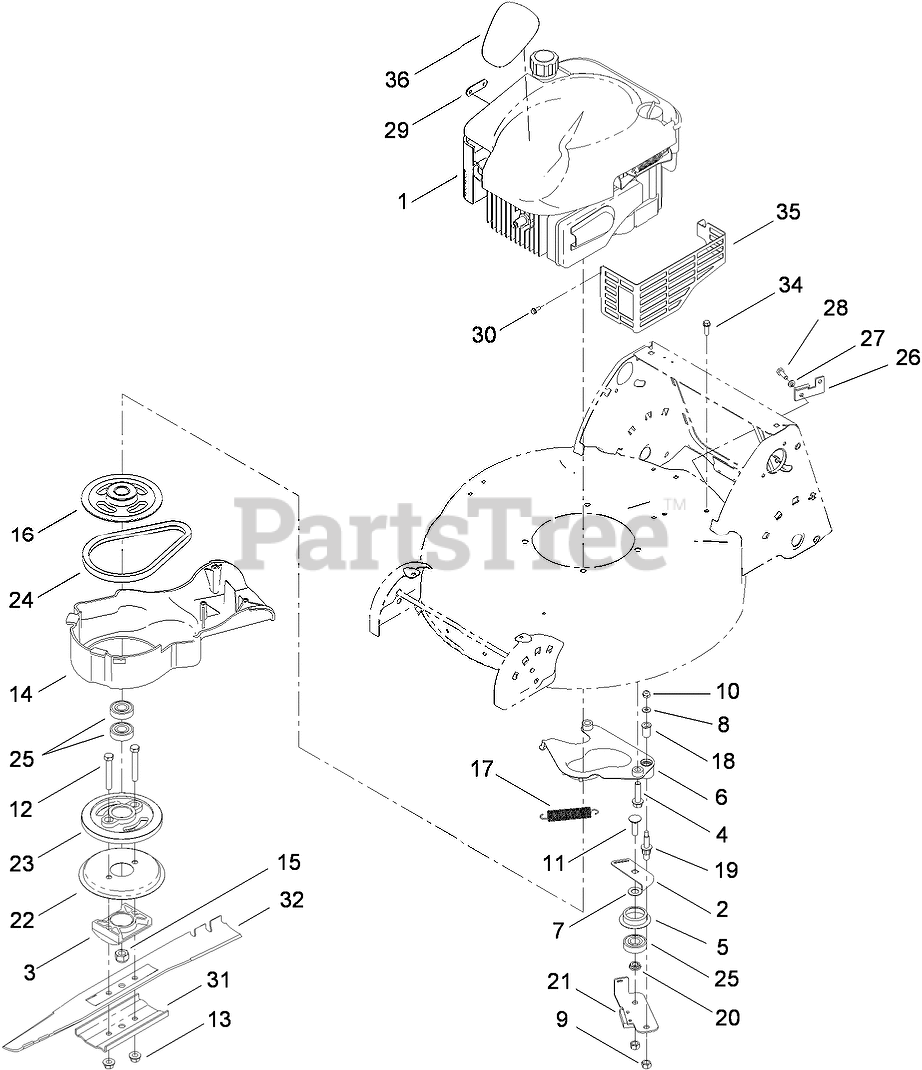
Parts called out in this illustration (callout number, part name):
2	PLATE-GUIDE
3	SUPPORT-BLADE
4	SCREW-HWH
5	RETAINER-BELT
6	PLATE-ANCHOR
7	WASHER-PLAIN
8	WASHER-FLAT
10	NUT-LOCK, NI
11	BOLT-CARR
12	SCREW-HH
13	NUT-LOCK
14	COVER-BBC
15	NUT-HEX
16	PULLEY
17	SPRING-TENSION, BRAKE
18	BUSHING
19	BOLT-SHOULDER
20	SPACER-BEARING
21	BRAKE ARM ASM
22	DISC
23	DRUM
24	BELT
25	BEARING-BALL
26	CLAMP-CABLE, BBC
27	WASHER-LOCK
28	SCREW-HH
29	PLATE-TERMINAL
30	SCREW-TAPTITE
31	SUPPORT-BLADE
32	BLADE-21 INCH
34	SCREW-HWH
35	SHIELD-MUFFLER
36	DECAL-ENGINE
